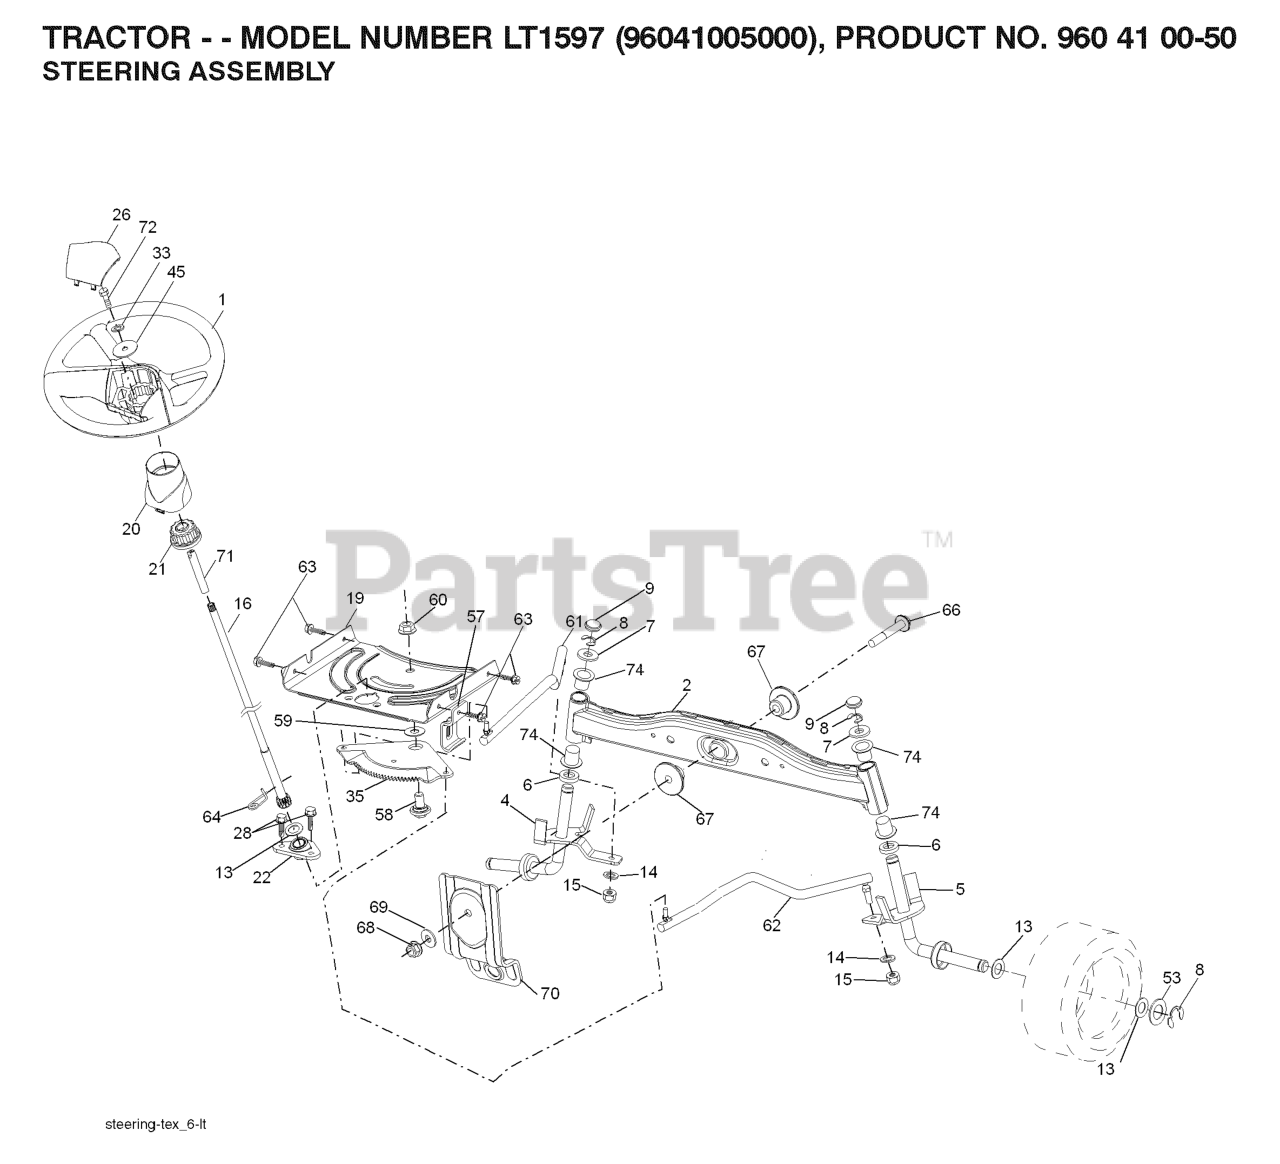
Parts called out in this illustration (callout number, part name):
1	WHEEL.STEERING.LEGEND2.GRY
4	SPINDLE.WELDED.LH.15"TEX
5	SPINDLE.WELDED.RH.15"T
6	THRUST WASHER
9	CAP.SPINDLE.BLACK
14	WASHER, LOCK 3/8
15	NUT CROWNLOCK 3/8-24
16	SHAFT STEERING
19	PLATE.STEER.DDL.NLT/NG
20	BOOT, STEERING
21	ADAPTER, WHEEL STNG..
22	BUSHING.ASM.STEERING.A
26	INSERT.CAP.STRG.WH.GRAY
28	SCREW, 3/8-16X3/4
33	WASHER.LOCK.HVY.HLCL.SPR.5/16
35	GEAR.SECTOR.PLATE.DDL.
45	WASHER.11/32
53	WASHER.HARDENED
57	BRACKET.UPSTOP.TEX
58	BOLT.SHOULDER.SECTOR.P
59	WASHER.THURST.SECTOR.S
60	NUT FLANGE LOCK 5/8-11
61	DRAGLINK.LH.BALLSTUD.D
62	DRAGLINK.RH.BALLSTUD.D
63	SCREW
64	RETAINER.CLIP.SPRING.S
66	BOLT HEX FGHD 7/16-14 X 3 SERR
67	BUSHING.PM.FRONT AXLE
68	NUT.LOCK.FLANGE.7/16
69	WASHER.1.5X.505X.118
70	BRKT.DECK.SUSPENSION.F
71	SHAFT EXTENSION STEERING
72	BOLT YT
74	BRNG T
